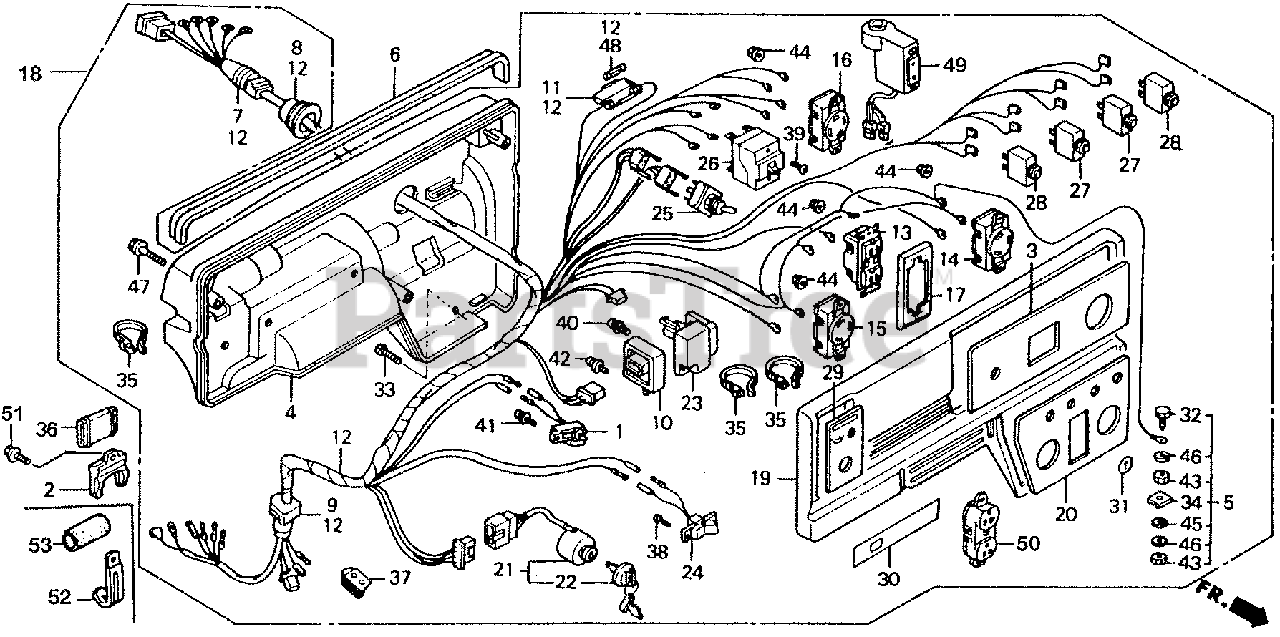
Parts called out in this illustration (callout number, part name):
3	MARK, SWITCH PANEL
4	CASE, CONTROL *R280* (POWER RED)
5	TERMINAL SET, GROUND
6	RUBBER, CONTROL
7	GROMMET, A.C. WIRE
8	GROMMET, MAIN WIRE
9	GROMMET, SWITCH WIRE
10	DIODE ASSY.
11	CASE, FUSE CONNECTOR (SUMITOMO)
12	WIRE HARNESS ASSY. (EB-A)
14	RECEPTACLE (20A/125V)
15	RECEPTACLE (30A/125V)
15	RECEPTACLE (3-PRONG) (30A/125V)
16	RECEPTACLE (30A/125-250V)
18	BOX ASSY., CONTROL *R8* (BRIGHT RED)
18	BOX ASSY., CONTROL *R280* (POWER RED)
19	PANEL, CONTROL *R280* (POWER RED)
20	MARK, A.C. OUT
21	SWITCH ASSY., COMBINATION
22	KEY
23	THROTTLE UNIT, AUTO (SAWAFUJI)
24	SWITCH, AUTO THROTTLE
25	SWITCH ASSY., VOLT CHANGE
26	BREAKER, CIRCUIT (23A)
27	PROTECTOR, CIRCUIT (20A)
28	PROTECTOR, CIRCUIT (30A)
29	MARK, ENGINE SWITCH
30	MARK, AUTO-THROTTLE
31	MARK, GROUND
32	BOLT, HEX. (6X28)
33	SCREW, GLOVE BOX
34	RETAINER (6MM)
35	TIE, CABLE
37	GROMMET, TUBE
38	SCREW, PAN (3X6)
39	SCREW, PAN (4X6)
40	SCREW-WASHER (5X12)
42	SCREW-WASHER (4X12)
43	NUT, HEX. (6MM)
44	NUT, FLANGE (4MM)
45	WASHER, PLAIN (6MM)
46	WASHER, SPRING (6MM)
47	BOLT, FLANGE (6X40)
48	FUSE B (10A)
49	RELAY ASSY. (GFCI)
50	RECEPTACLE (20A/125V) (MATSUSHITA)
51	BOLT, FLANGE (6X12) (CT200)
52	CLIP, WIRE HARNESS
53	TUBE, CORD
